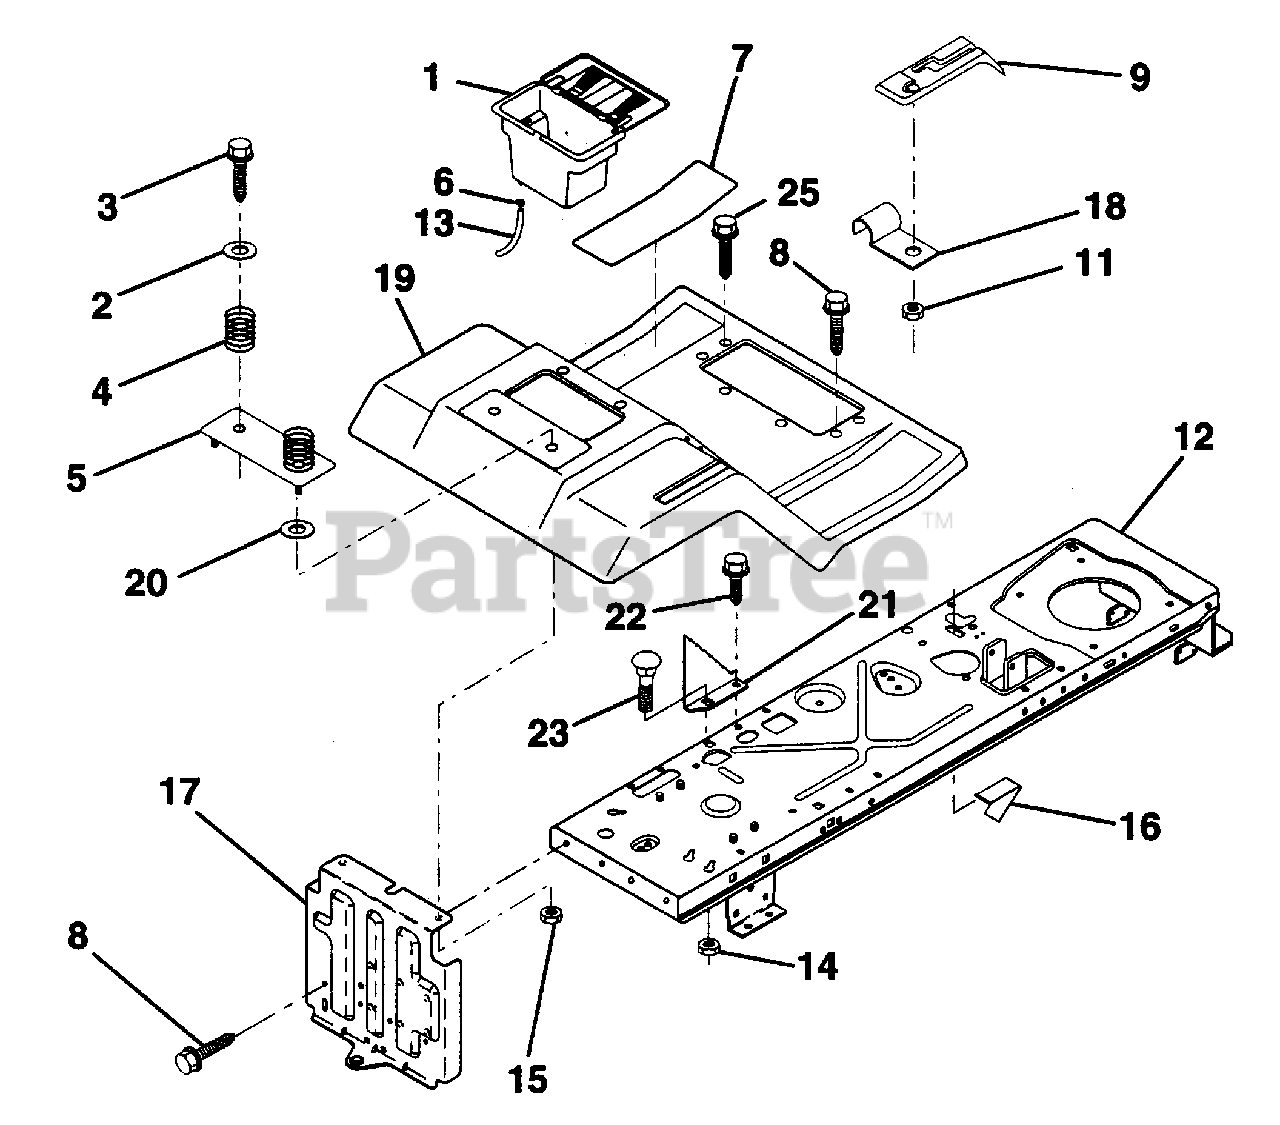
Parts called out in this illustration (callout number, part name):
1	Case, Battery (AYP part number)
2	Washer 13/32 x 1-1/4 x 12 Ga. (AYP part number)
3	Screw, Hex Wsh. Thrdrol. 3/8-16 x 3/4 (AYP part number)
4	Spring, Compression, Seat (AYP part number)
5	Plate, Asm. Battery (AYP part number)
6	Clamp, Hose (AYP part number)
7	Pad, Footrest (AYP part number)
8	Screw, Hex Wsh Thdrol. 5/16-18 x 3/4
9	Console, Shift Control (AYP part number)
11	Nut, Self-Thrd., Wsh. Head 3/16 (AYP part number)
12	Chassis Asm. Weldment
13	Tube, Battery Drain (AYP part number)
14	Locknut, Hex w/Insert 5/16-18 Unc
15	Nut, Keps Hex 1/4-20 UNC (AYP part number)
16	Switch Actuator (AYP part number)
17	Drawbar (AYP part number)
18	Clip, Insulated (AYP part number)
19	Fender/Footrest (AYP part number)
20	Washer 9/32 x 7/8 x 13 Ga. (AYP part number)
21	Bracket, Stop (AYP part number)
22	Screw 5/16-18 x 1/2 (AYP part number)
23	Bolt, Carriage 5/16-18 x 3/4 (AYP part number)
25	Screw Hex 5/16-18 x 1 (AYP part number)
